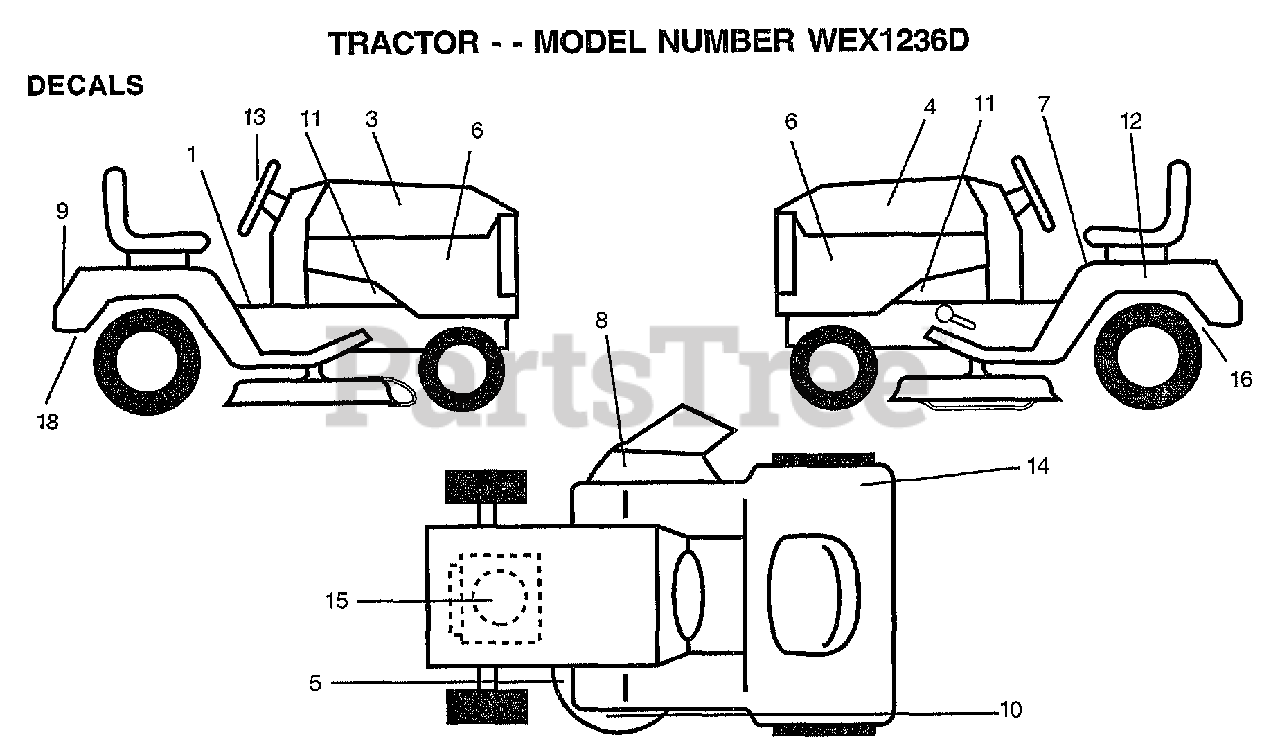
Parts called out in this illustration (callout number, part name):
1	DECAL CLUTCH/BRAK
3	DECAL.HOOD.RH
4	DECAL.HOOD.LH
5	DECAL.V.BELT
6	DECAL.PNL.SIDE
7	DECAL.READ.O.MANU
8	DECAL.DANGER.CUTF
9	DECAL.FENDER.LOGO
10	DECAL, DECK GRASSEATER
11	"DECAL CHASSIS,HOT"
12	DECAL.BATRY.3-3908
13	DECAL INSRT STEER
15	DECAL, ENGINE
16	DECAL.DRAWBAR.LDL
18	DECAL.EURO.ST.CE.
